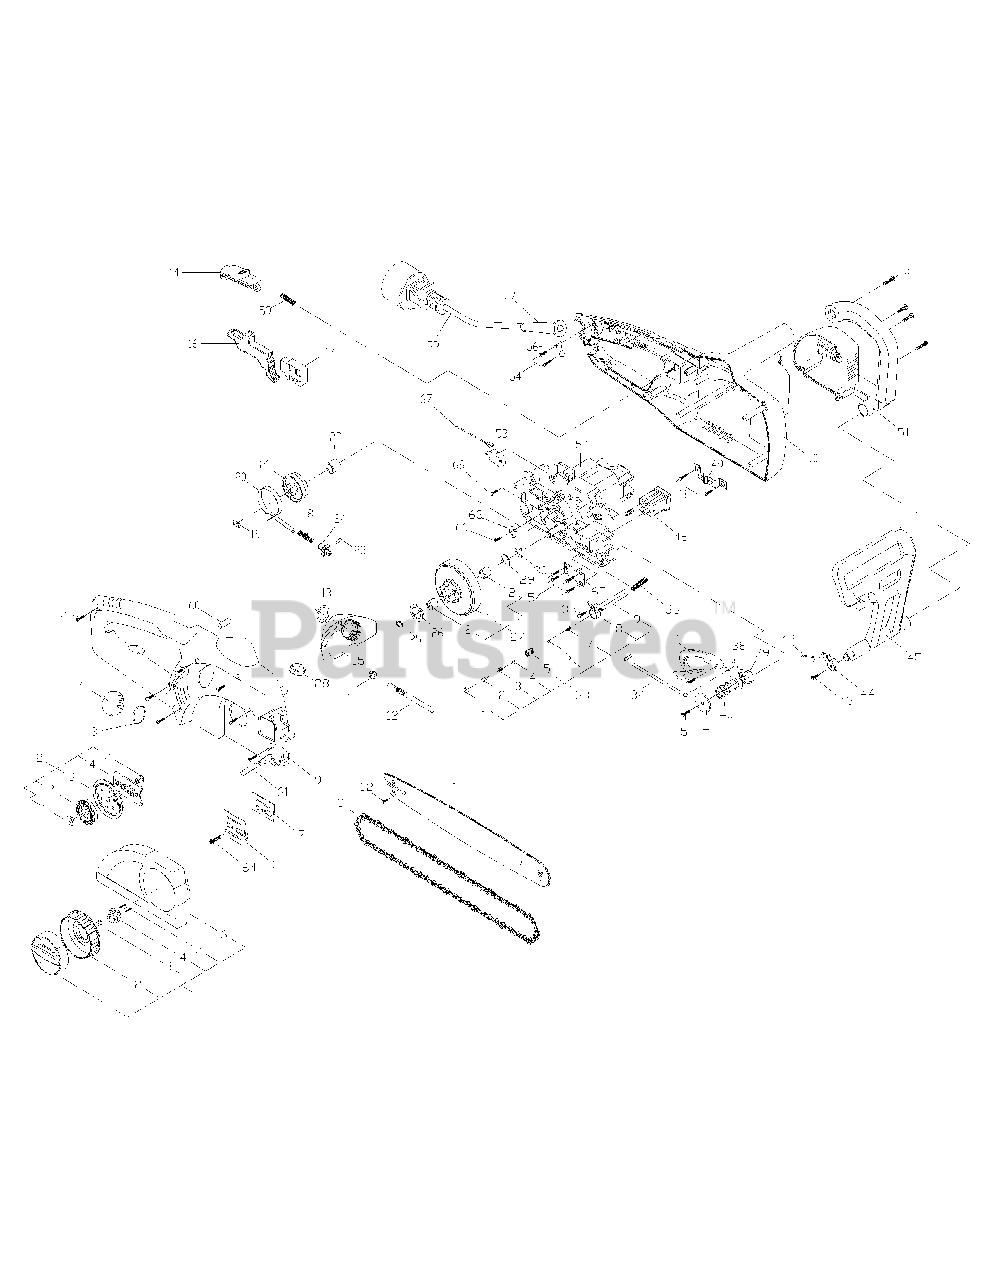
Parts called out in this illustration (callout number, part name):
1	HOUSING (R)
2	CHAIN COVER ASS'Y
4	OIL COVER
6	ADJUSTMENT PLATE
7	OIL WASHER
9	HOUSING (R)
12	OIL PIPE ASS'Y
14	SWITCH BUTTON
20	SPRING, BRAKE
22	ADJUSTMENT COVER
24	CONNECTION
27	GEAR BEARING ASS'Y
30	C RING
33	OIL PUMP ASS'Y
35	PULL PLATE
42	CONNECTING BAR
44	CONNECTOR
45	FRONT-HAND GUARD
46	FIXED ACC'Y
50	HOUSING (L)
51	REAL COVER
52	MOTOR GEAR BOX ASS'Y
55	POWER CORD
56	STRAIN RELIEF
57	CORD GUARD
58	RUBBER STOP
